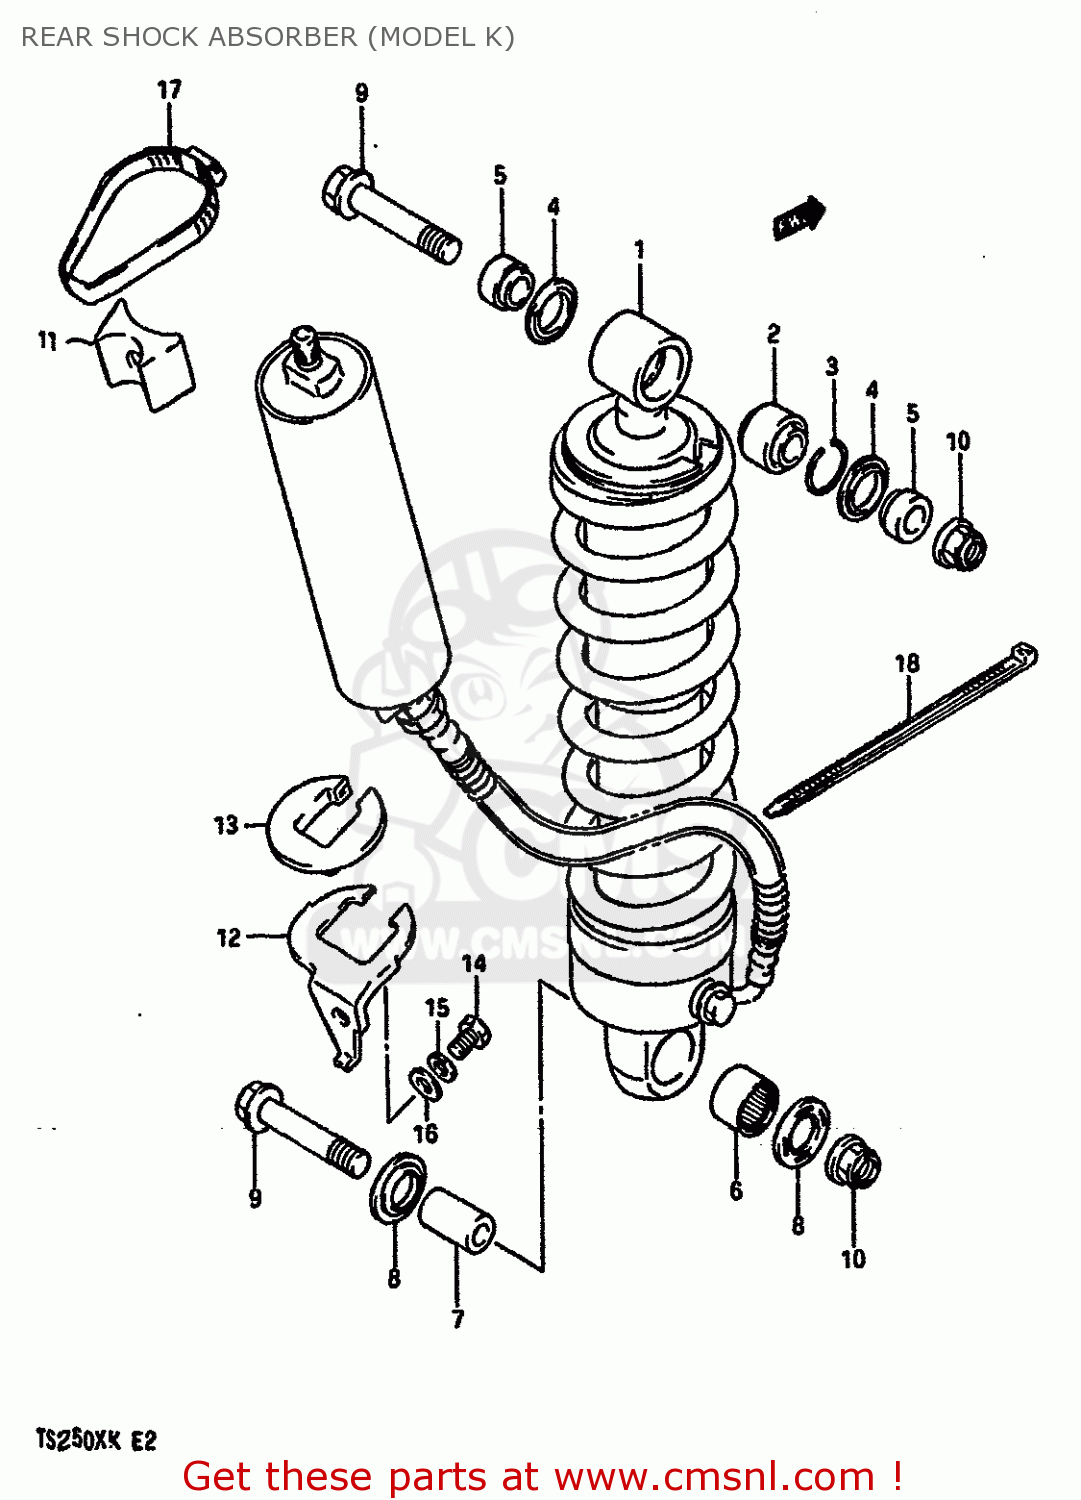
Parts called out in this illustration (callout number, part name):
1	ABSORBER ASSY,REAR SHOCK (BLUE)
2	BEARING,REAR SHOCK ABSORBER
3	RING
4	SEAL,DUST RR SHOCK ABSORBER
5	COLLAR
6	BEARING,NEEDLE
7	COLLAR
8	SEAL,DUST
9	BOLT(10X54)
10	NUT
11	CUSHION,RESERVOIR TANK UPR
12	BRACKET,LOWER
13	CUSHION,LOWER
14	BOLT
15	WASHER,LOCK
16	WASHER
17	CLAMP
18	CLAMP(L:145)
